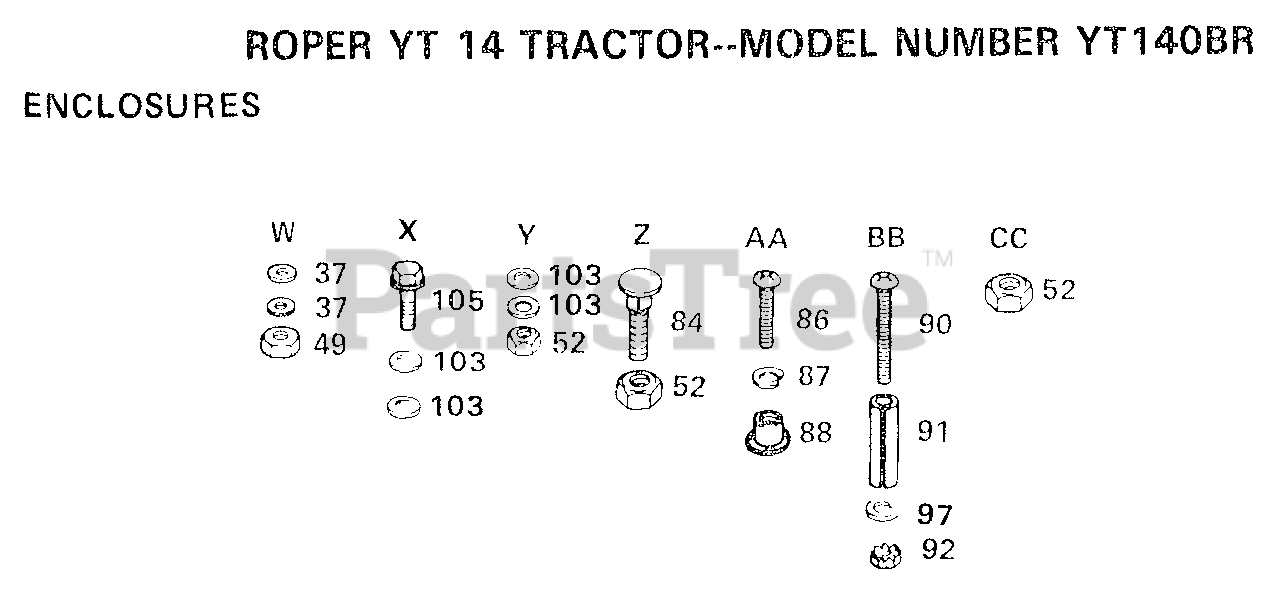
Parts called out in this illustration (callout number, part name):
37	WASHER PM
84	BOLT
86	SCREW
87	LOCKWASHER
88	WELDNUT
90	SCREW
91	SPACER LT
97	WASHER
103	WASHER
105	SCREW GTV
